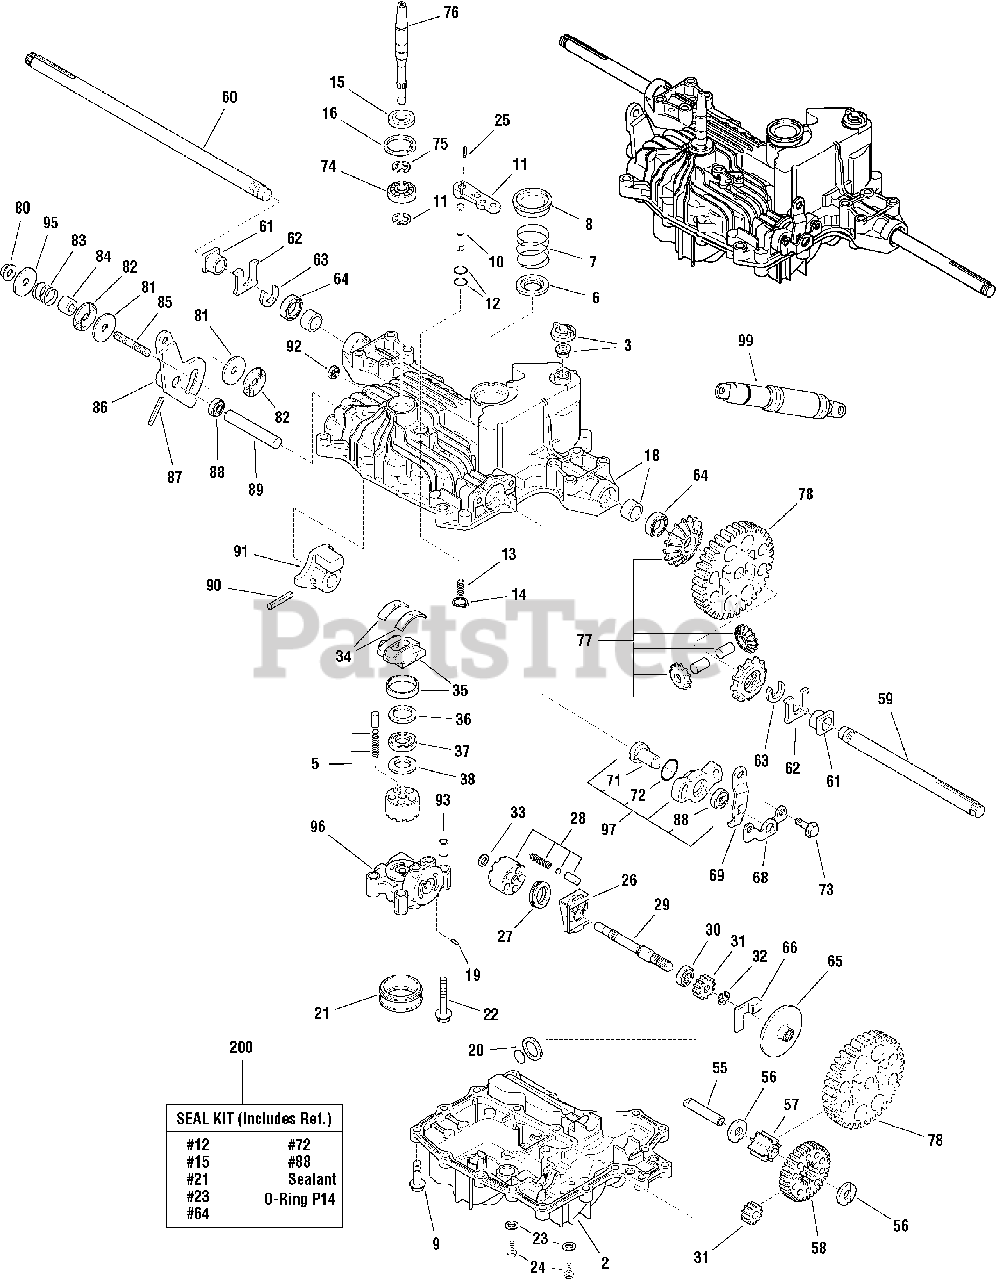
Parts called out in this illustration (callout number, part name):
2	LOWER HOUSING
5	*CYLINDER BLOCK, Complete
7	SPRING, Filter
8	SEALING CAP
9	SCREW, Tapping
10	SHAFT , Bypass
11	LEVER , Bypass
12	O-RING, 1A P10A
13	*SPRING
15	SEAL, TC
18	*UPPER HOUSING, Complete
21	FILTER
23	WASHER, Seal 8
24	BOLT 8 x 12
28	CYLINDER BLOCK CMP.
29	MOTOR SHAFT
30	BEARING
31	*MOTOR GEAR
34	THRUST METAL BEARING
35	SWASH PLATE CMP.
36	THRUST PLATE B
38	THRUST PLATE A
55	*REDUCTION SHAFT
56	*WASHER
57	FINAL PINION
58	*REDUCTION GEAR
59	*AXLE SHAFT, Left
60	AXLE SHAFT, Right
62	THRUST WASHER
64	SEAL
65	DISK, Brake
66	SHOE, Brake
68	PLATE, Brake
69	*ARM, Brake
71	SHAFT, Brake
73	*BOLT
75	RING
77	DIFF. GEAR KIT
78	*FINAL GEAR
81	FRICTION PLATE, Complete
83	SPRING, Friction
86	CONTROL LEVER
87	PIN
89	*CONTROL SHAFT
91	CONTROL ARM ASSEMBLY
92	CAP, Sealing
96	CENTER CASE B CMP.
97	KIT, Brake Cam
99	SHOCK ABSORBER
200	K51/K56 SEAL KIT
